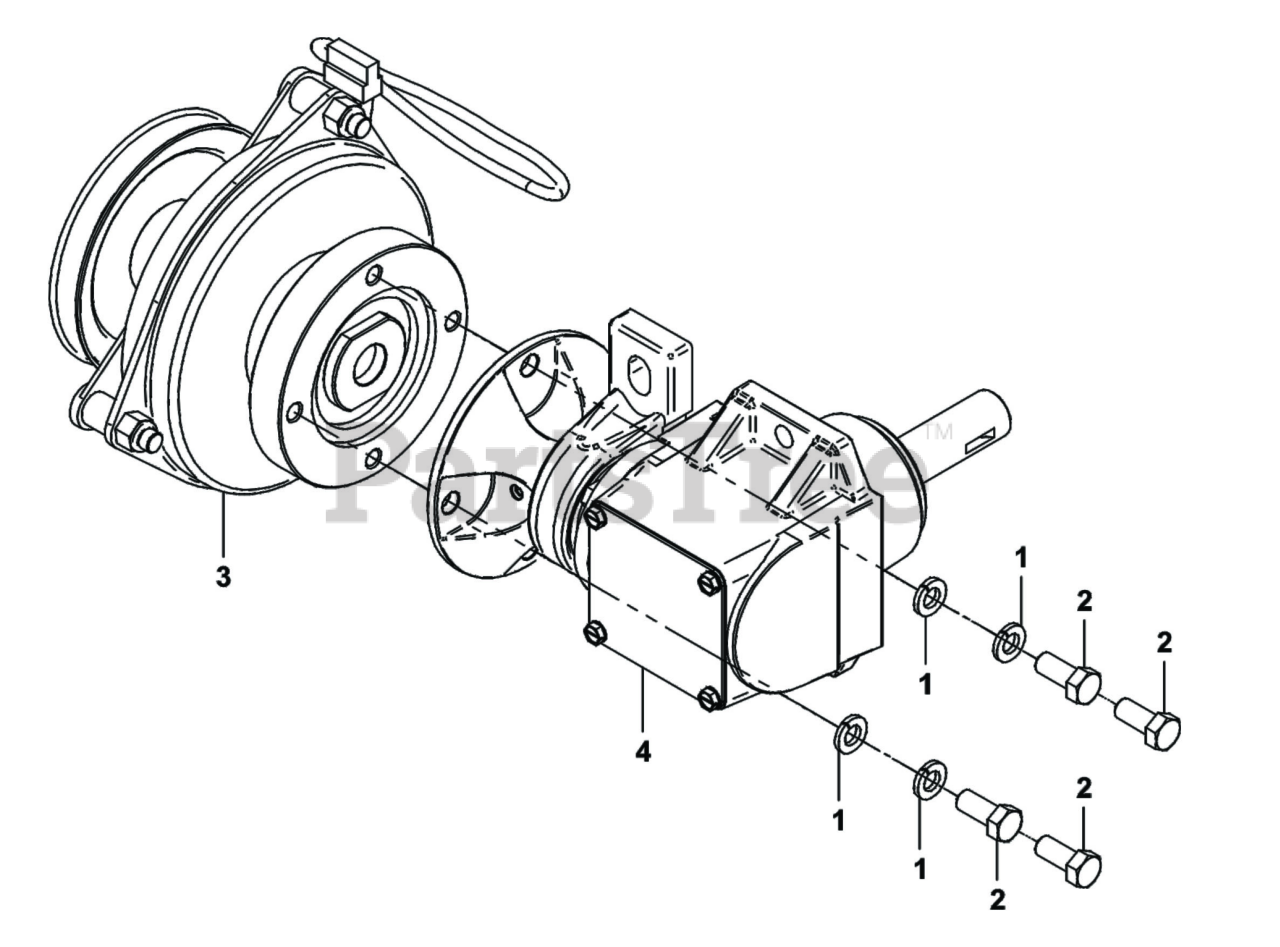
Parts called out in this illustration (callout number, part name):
1	LOCK WASHER 3/8
2	SCREW 3/8"-16 x .875" (GR8)
3	Clutch Sub-Assy
4	GEARBOX SUB ASSEMBLY
